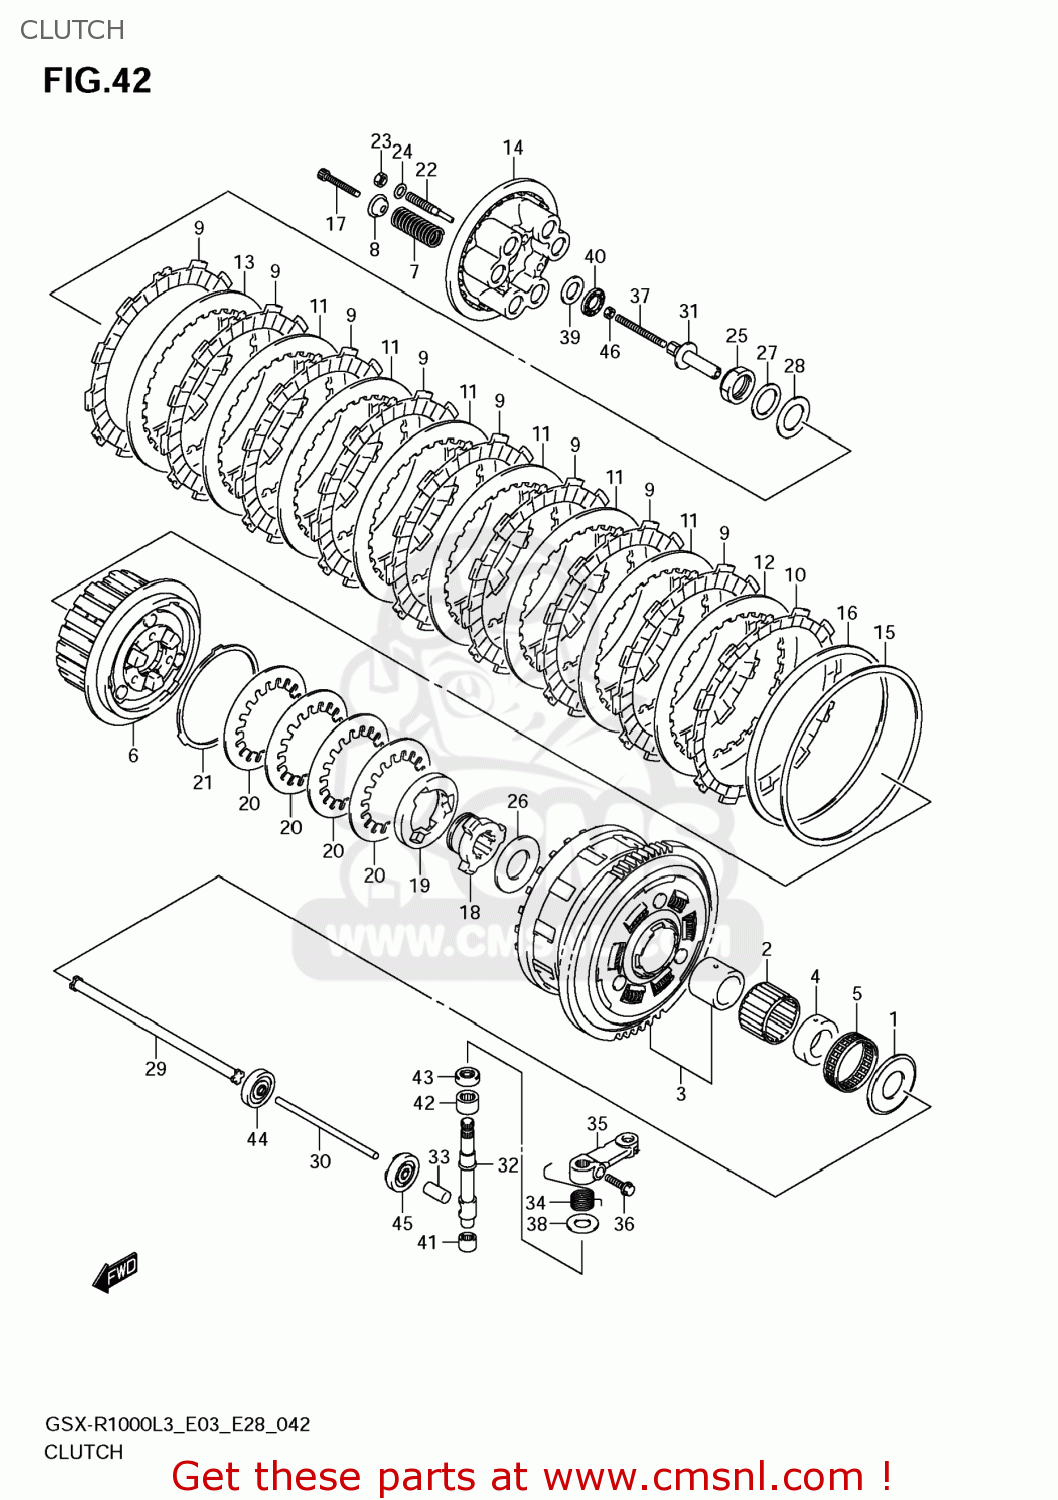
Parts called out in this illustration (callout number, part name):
1	WASHER(25X54X2.4)
2	BEARING(35X40X26.8)
3	GEAR ASSY,PRI DRIVEN
4	SPACER,OIL PUMP DRIVE SPROCKET
5	BEARING(35X40X12)
6	HUB,CLUTCH SLEEVE
7	SPRING,CLUTCH
8	WASHER
9	PLATE,CLUTCH DRIVE NO.1 (NAS)
10	PLATE,CLUTCH DRIVE NO.2 (NAS)
11	PLATE,CLUTCH DRIVEN NO.1 (NAS)
12	PLATE,CLUTCH DRIVEN NO.2 (NAS)
13	PLATE,CLUTCH DRIVEN NO.3 (NAS)
14	DISC,CLUTCH PRESSURE
15	SEAT,WAVE WASHER
16	WASHER,CLUTCH PLATE WAVE
17	BOLT,CLUTCH SPRING
18	CAM,CLUTCH DRIVE
19	CAM,CLUTCH DRIVEN
20	WASHER,CAM REACTION WAVE
21	WASHER,CAM REACTION SEAT
22	LIFTER,CLUTCH PRESSURE DISC
23	NUT,CL PRESS DISC LIFTER LOCK
24	SHIM(8.8X14X1)
25	NUT
26	WASHER(25X50X2.5)
27	WASHER(25X41X2.5)
28	WASHER
29	ROD,CLUTCH
30	ROD,CLUTCH PUSH,L
31	PIECE,CLUTCH PUSH
32	CAMSHAFT,CLUTCH RELEASE
33	CAP,CLUTCH PUSH ROD
34	SPRING,CLUTCH RELEASE RETURN
35	ARM,CLUTCH RELEASE
36	BOLT(6X20)
37	SCREW(6X73)
38	WASHER(10.5X24X1)
39	WASHER(15.5X28X1)
40	BEARING(15X28X2)
41	BEARING(10X14X10)
42	BEARING(12X18X12)
43	SEAL,OIL(10X20X6)
44	SEAL,OIL(6X34X10.5)
45	SEAL,OIL(10X17X5)
46	NUT
